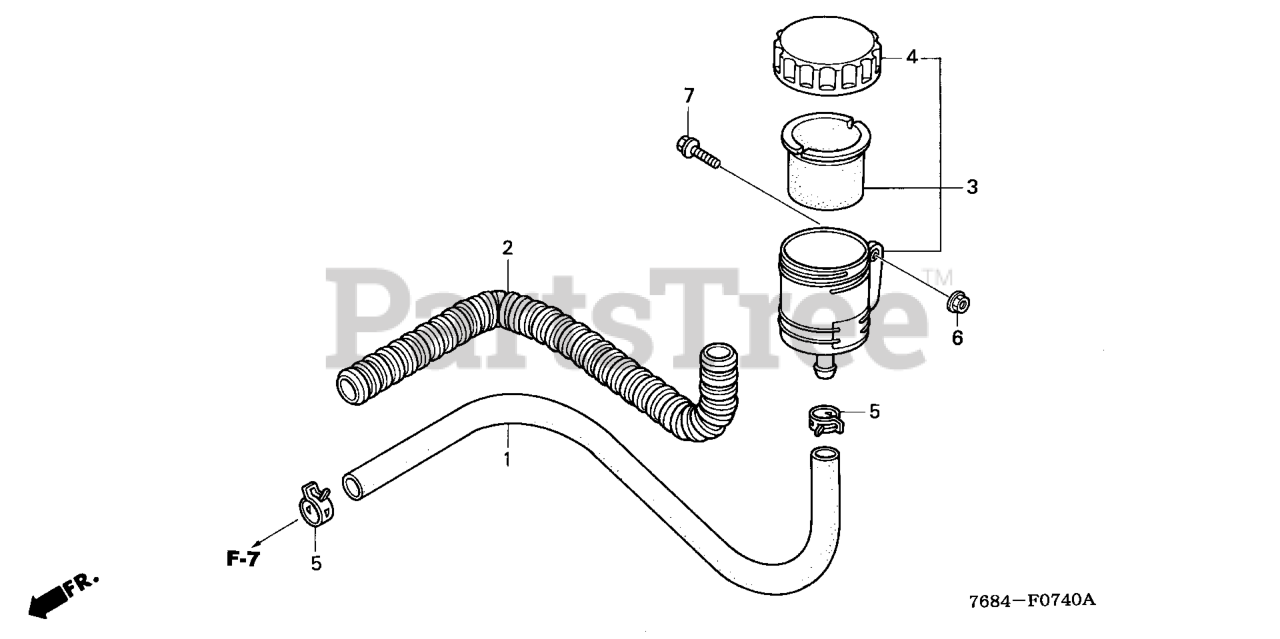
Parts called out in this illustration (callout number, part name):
2	PROTECTOR, OIL TUBE
3	TANK ASSY., OIL
4	FRAME, OIL CAP
5	CLAMP D (19MM)
6	NUT, FLANGE (6MM)
7	BOLT, FLANGE (6X16) Use from Engine SN 2056820.
